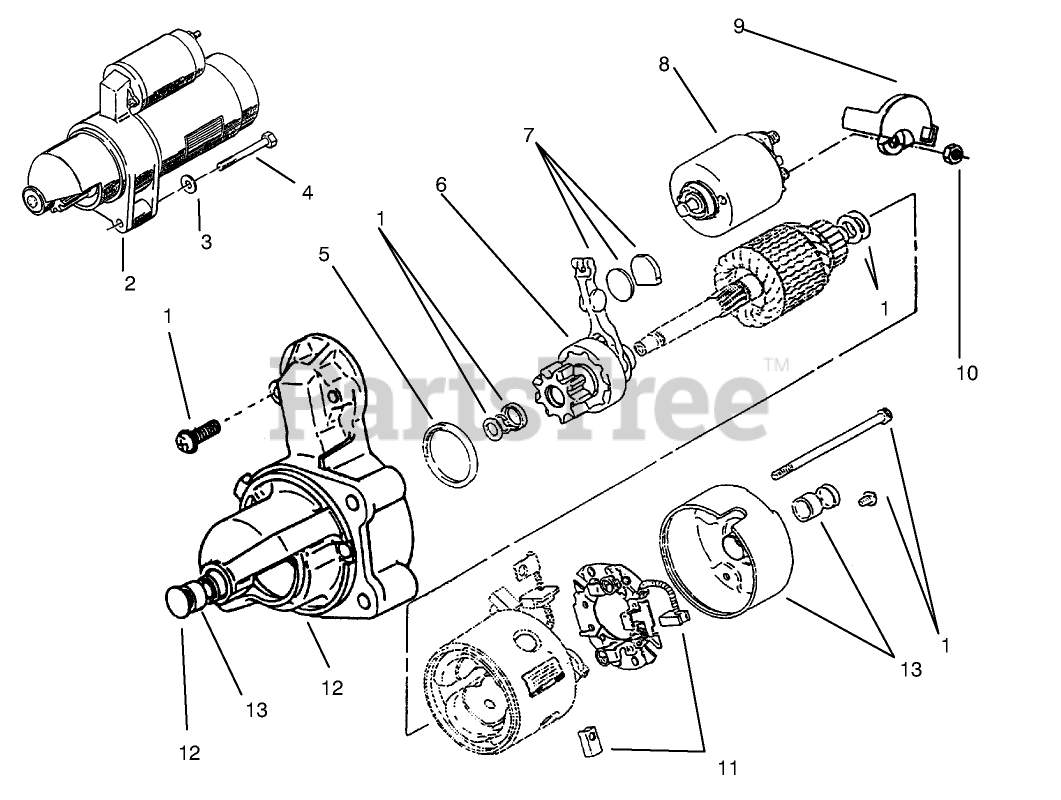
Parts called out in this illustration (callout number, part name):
3	WASHER
6	CLUTCH STARTER ASSEMBLY
8	STARTER SOLENOID KIT
10	HEX NUT
12	KIT-MTG BRKT
13	BUSHING
